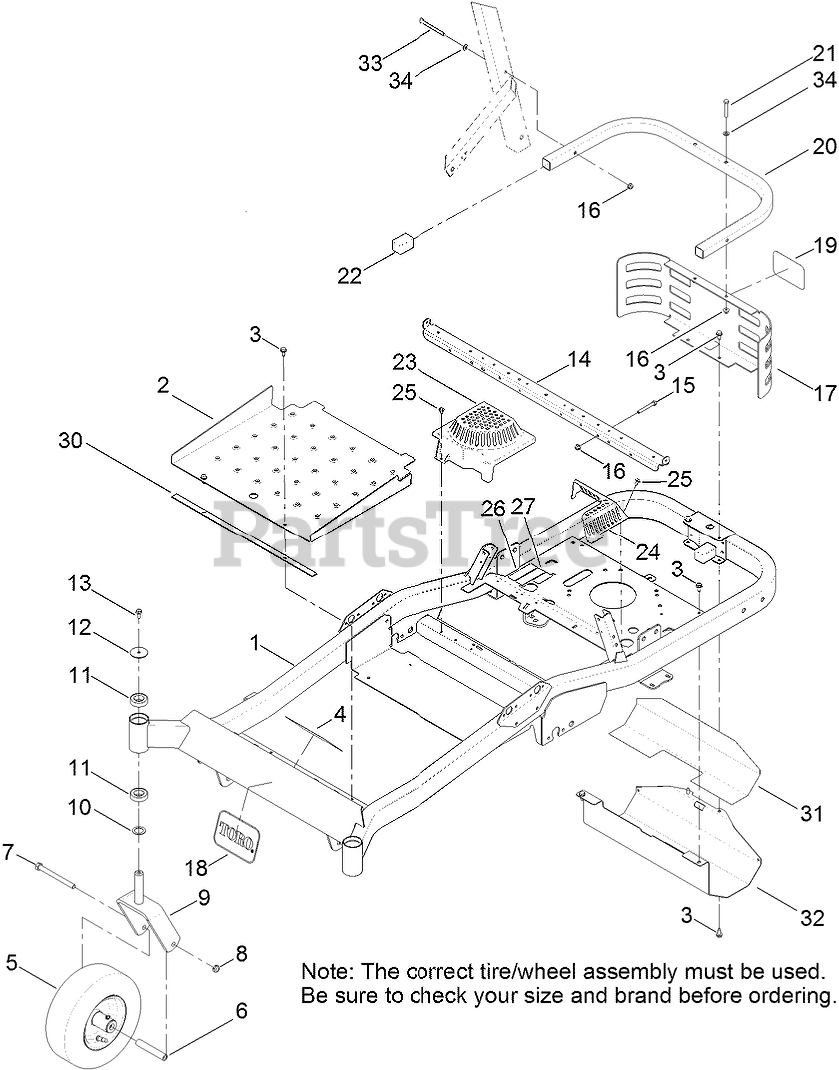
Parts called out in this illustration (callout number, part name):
2	PAN-FLOOR
3	SCREW-HWHTF
4	DECAL-SAFETY
5	TIRE AND WHEEL ASM (C S T)
5	Tire and Wheel ASM (Kenda)
6	BUSHING-SPANNER
7	SCREW-HH
8	NUT-LOCK, NI
9	CASTER FORK ASM
10	WASHER-THRUST
11	BEARING-BALL
12	WASHER
13	SCREW-HHF
14	SUPPORT-SEAT
15	SCREW-HH
16	NUT-HF, NI
17	GUARD-REAR
18	DECAL
20	TUBE-GUARD
21	SCREW-HH
23	COVER-FAN, RH
24	COVER-FAN, LH
25	SCREW-HHFTF
26	DECAL-SERIAL
27	DECAL-EMISSIONS, E P A
30	STRIP-VIBRATION, ANTI
31	FOIL-HEAT SHIELD
32	GUARD-MUFFLER
33	SCREW-HH
34	WASHER-PLAIN
